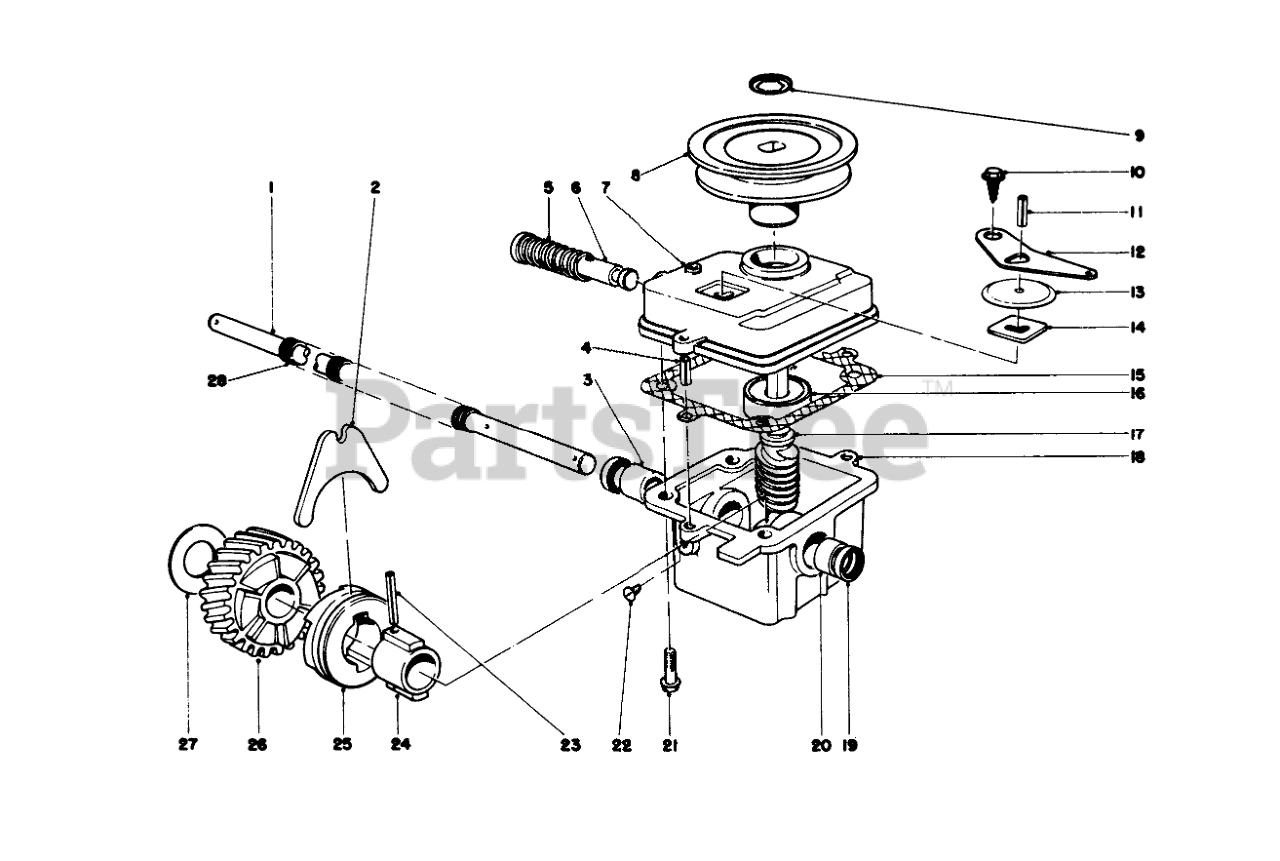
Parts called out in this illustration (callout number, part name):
1	DRIVE SHAFT (SERVCE)
2	SHIFTER FORK
3	Bushing
4	3/16 X 1/2 ROLL PIN
5	SPRING
6	Shift Rod
7	Cover Gear Case
8	PULLEY
9	PUSH-ON 93-3236
10	Screw
11	PIN-ROLL
12	SHIFTER ARM
13	TRANS DUST COVER
14	LATCH PLATE
15	GASKET
16	Bearing
17	Worm Shaft (Incl. Ref. #26)
18	Gear Case (Incl. Ref. #3, 19-20)
19	Seal
20	Bushing
21	Screw
22	NYLON SCREW
23	Pin
24	SLEEVE
25	CLUTCH JAW
26	Helical Gear
27	THRUST WASHER
28	DRIVE SHAFT COVER
